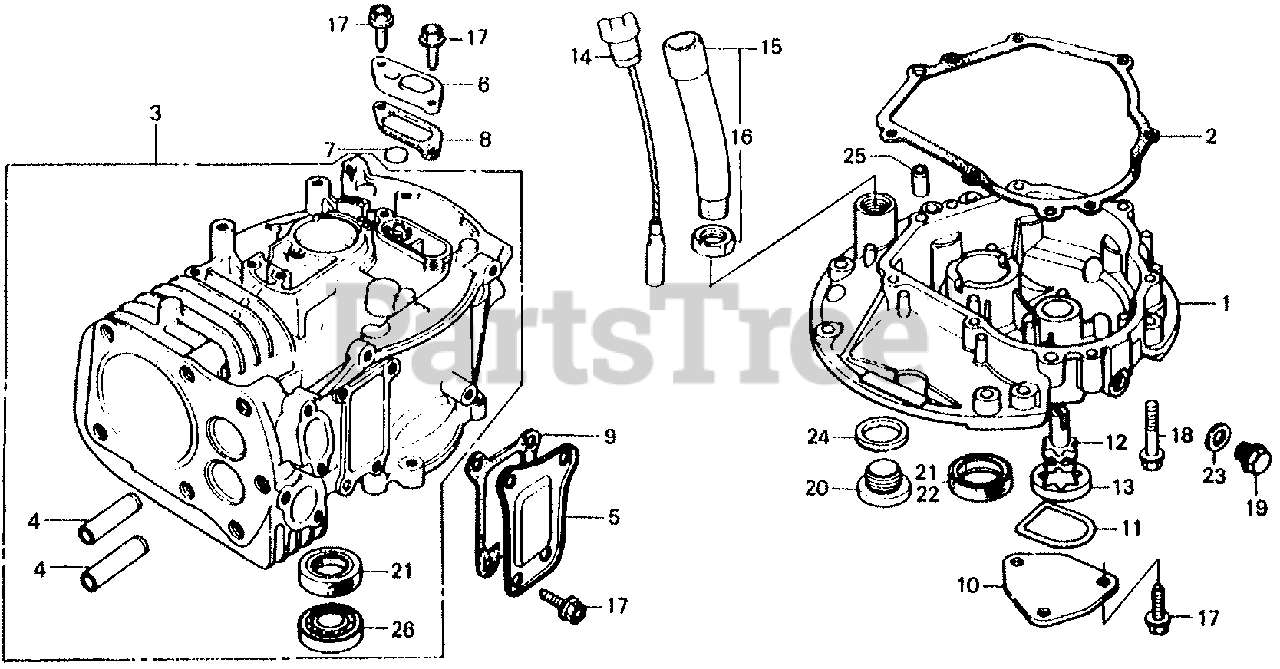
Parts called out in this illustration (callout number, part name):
1	PAN, OIL
2	GASKET, OIL PAN (Honda Code 0671677). (NOT AVAILABLE)
3	CYLINDER ASSY.
4	GUIDE, VALVE (OS)
5	COVER, TAPPET
6	CAP, BREATHER CHAMBER
7	VALVE, BREATHER
8	GASKET, BREATHER CAP
9	GASKET, TAPPET COVER
10	COVER, OIL PUMP
11	O-RING, COVER
12	ROTOR (INNER)
13	ROTOR, OIL PUMP (OUTER)
14	CAP, OIL FILLER
15	PIPE, OIL FILLER
16	NUT, OIL FILLER
17	BOLT, FLANGE (6X12) (CT200)
18	BOLT, FLANGE (6X32)
19	BOLT, DRAIN PLUG
20	BOLT, DRAIN PLUG
21	OIL SEAL (25X41X6)
22	OIL SEAL (25X38X7)
22	OIL SEAL (25X38X7) (ARAI)
23	WASHER, DRAIN PLUG (12MM)
24	WASHER, DRAIN PLUG (20MM)
25	PIN A, DOWEL (8X14)
26	BEARING, RADIAL BALL (6205)
